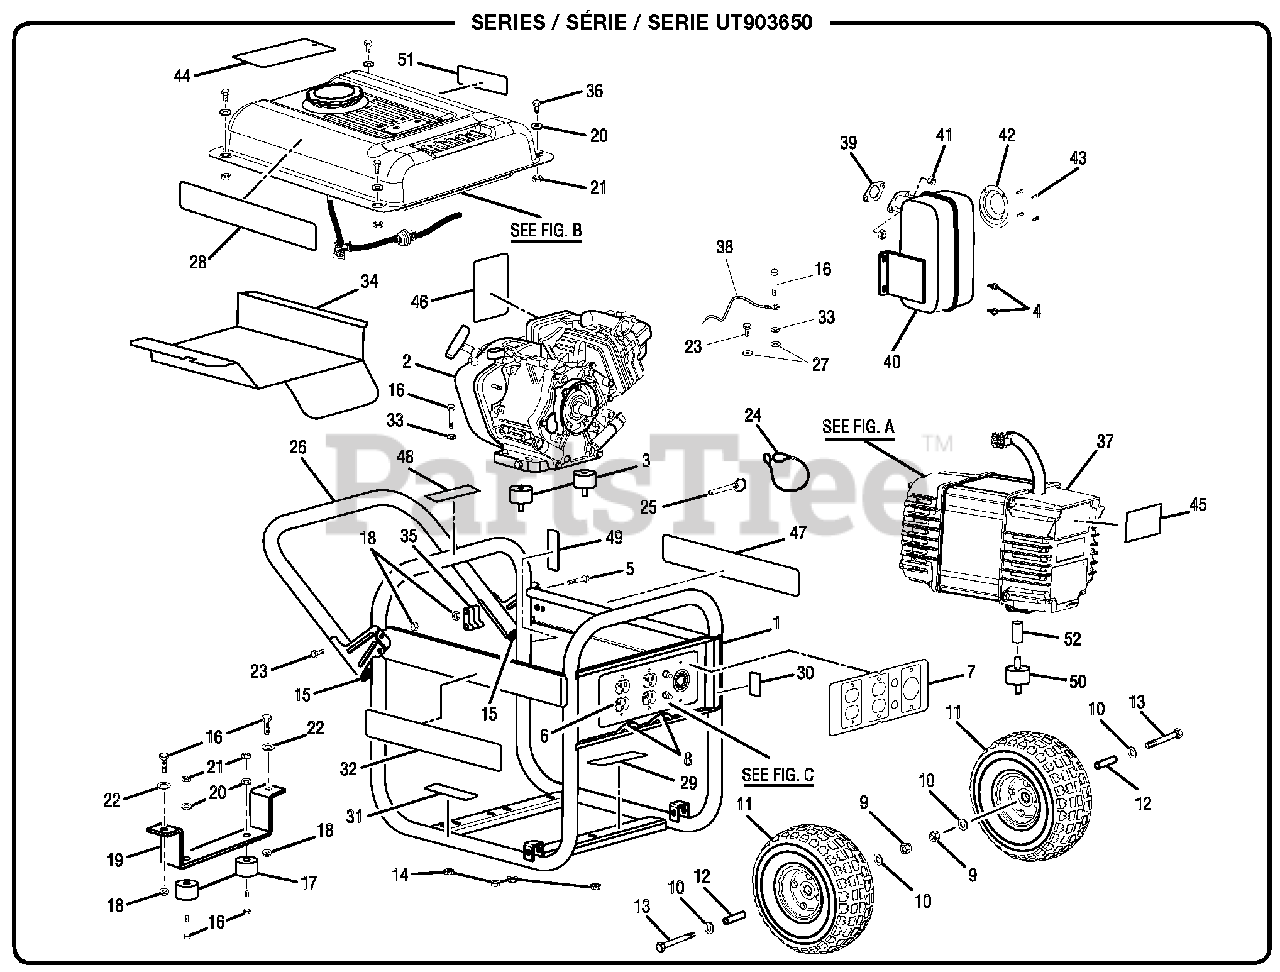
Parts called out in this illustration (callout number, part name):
1	Carrier Assembly
2	Engine (Subaru OHC)
4	Bolt (5/16-24 x 5/8 in)
5	Bolt (5/16-18 x 2-1/4 in, Hex Hd)
6	Control Panel (See Fig C)
7	Control Panel Label
8	Cord Retainer
9	Lock Nut (3/8-16)
10	Washer (3/8 in)
12	Spacer (3/8 in ID)
13	Bolt (3/8-16 x 4-1/4 in)
14	Lock Nut (5/16-18)
16	Bolt (5/16-18 x 1-1/2 in)
17	Rubber Foot
18	Flange Nut (5/16-18)
19	Foot Bracket
20	Washer (1/4 in)
21	Lock Nut (1/4-20)
22	Washer (5-16 in)
23	Bolt (5/16-18 x 3/4 in, Hex Hd)
25	Release Pin
27	External Star Washer (5/16 in)
28	CPSC Label
29	Ground Warning Label
30	Hot Surface Label
31	Engine Lubricant Label
32	Logo Label
33	Lock Washer (5/16 in)
34	Heat Shield
35	Handle Bracket Spacer
36	Bolt (1/4-20 x 1 in)
37	Generator Head Assembly (See Fig A)
38	Ground Wire Assembly
41	Hex Nut (8 mm)
42	Spark Screen
43	Screw (#8 x 3/8 in)
44	Danger Hang Tag
45	Data Label
46	Start Label
47	Danger Label
48	Fire Danger Label
49	Lock Pin Label
51	Combustion Label
52	Spacer (3/8 in ID)
